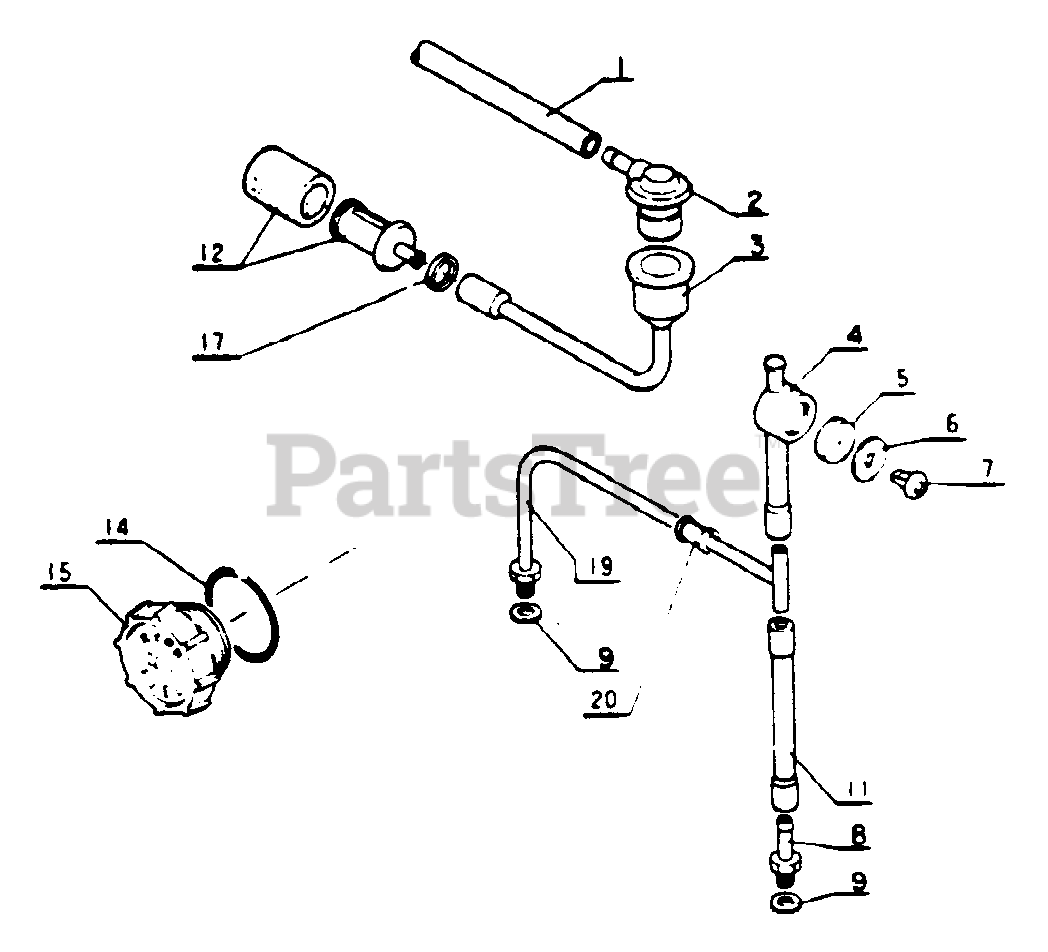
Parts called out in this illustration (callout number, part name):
1	PIPE - FUEL - OUTER
2	CONNECTOR, PIPE
3	PIPE - FUEL
4	PIPE - AIR
6	HOLDER, VENT
7	VALVE, CHECK
8	NIPPLE
11	CONNECTOR
12	FILTER, FUEL
14	O-RING
15	CAP
17	RETAINER, PIPE
19	PIPE - AIR
